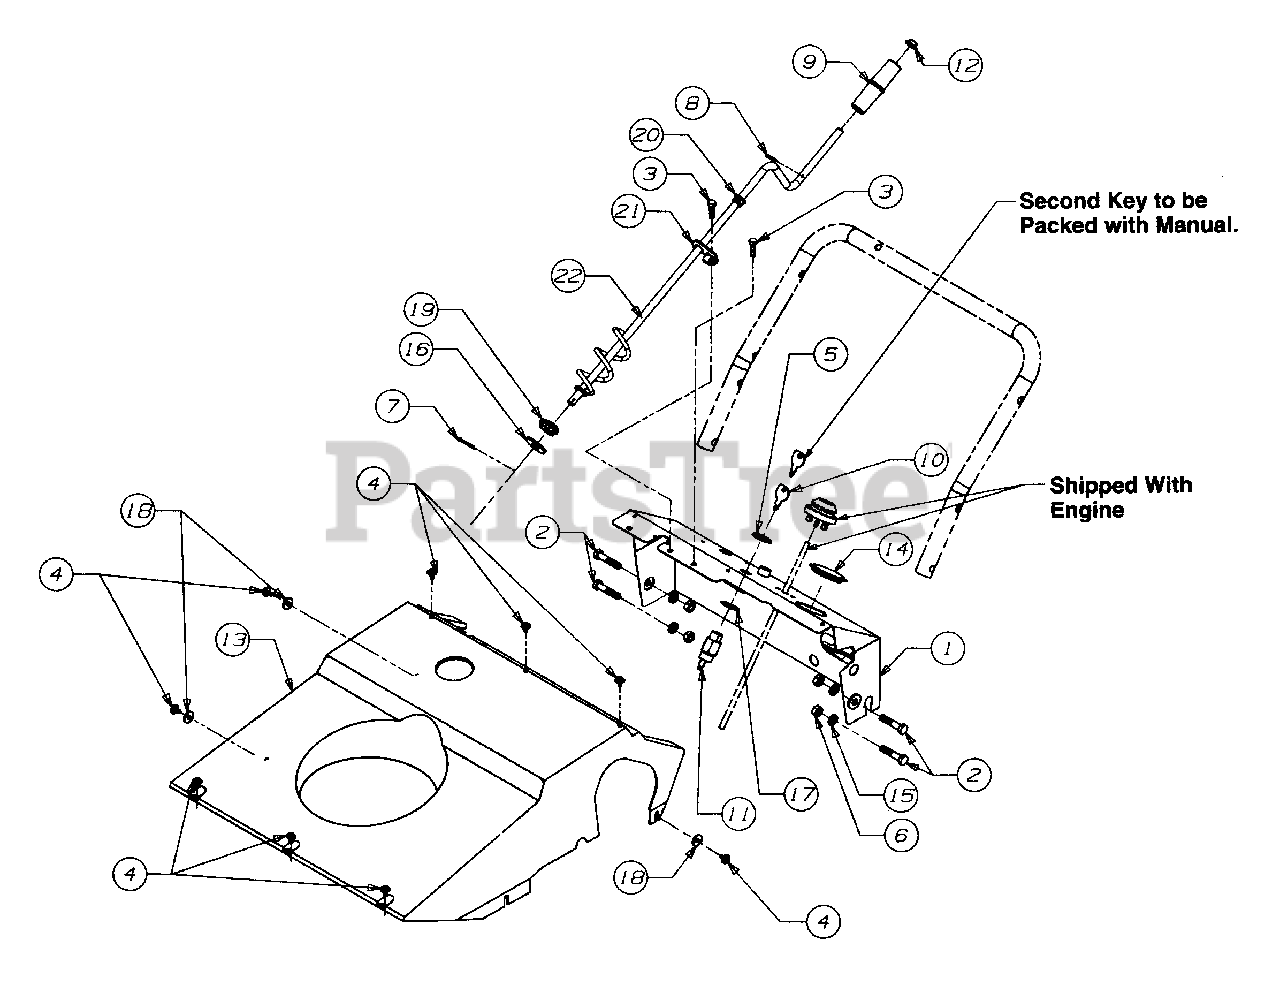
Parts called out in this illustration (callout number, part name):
3	Screw-Hex Tap
4	Screw-Hex Tap
5	Nut Hex
6	Nut-Hex
7	Pin-Cotter
8	Pin Roll
9	Knob-Chute Crank
10	Key-Ignition
11	Switch-Key
12	Nut Push
13	Shroud
15	Washer Lock
16	Washer Flat
17	Washer Internal Lock
18	Washer Flat
19	Bushing Hex
20	Bushing
21	Bracket Chute Crank
22	Crank Ass'y. Chute
